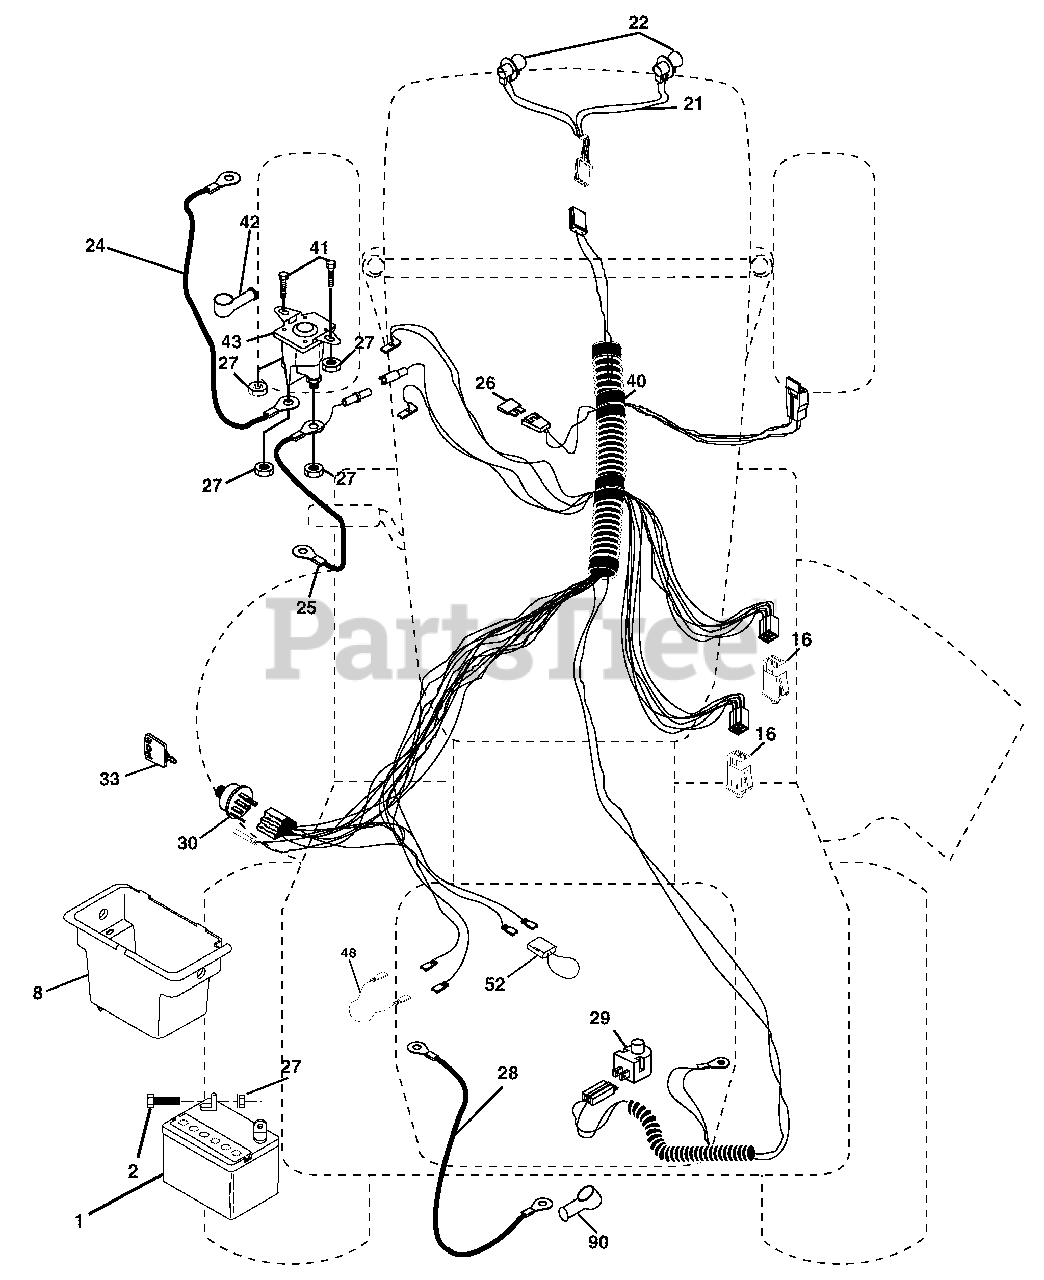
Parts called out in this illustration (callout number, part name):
1	Battery 12 Volt 25 Amp
2	Bolt Hex Hd 1/4-20 Unc x 3/4
8	Box Battery
16	Switch Interlock Push -In
21	Harness Asm Light W/4152J
22	Bulb Light #1156
24	Cable Battery 6 Ga 11" red
25	Cable Battery 6 Ga w/16 wire,red
26	Fuse 20 AMP
27	Nut Keps Hex 1/4-20 Unc
28	Cable Ground 6 Ga 12" black
29	Switch Plunger Nc Gray
30	Switch Ign
33	Key Ign
40	Harness Ign
41	Bolt Blk Fin Hex 1/4-20 x 1/2
42	Cover Terminal Red
43	Solenoid
48	Adapter Ammeter
52	Protection Wire Loop
90	Cover Terminal
